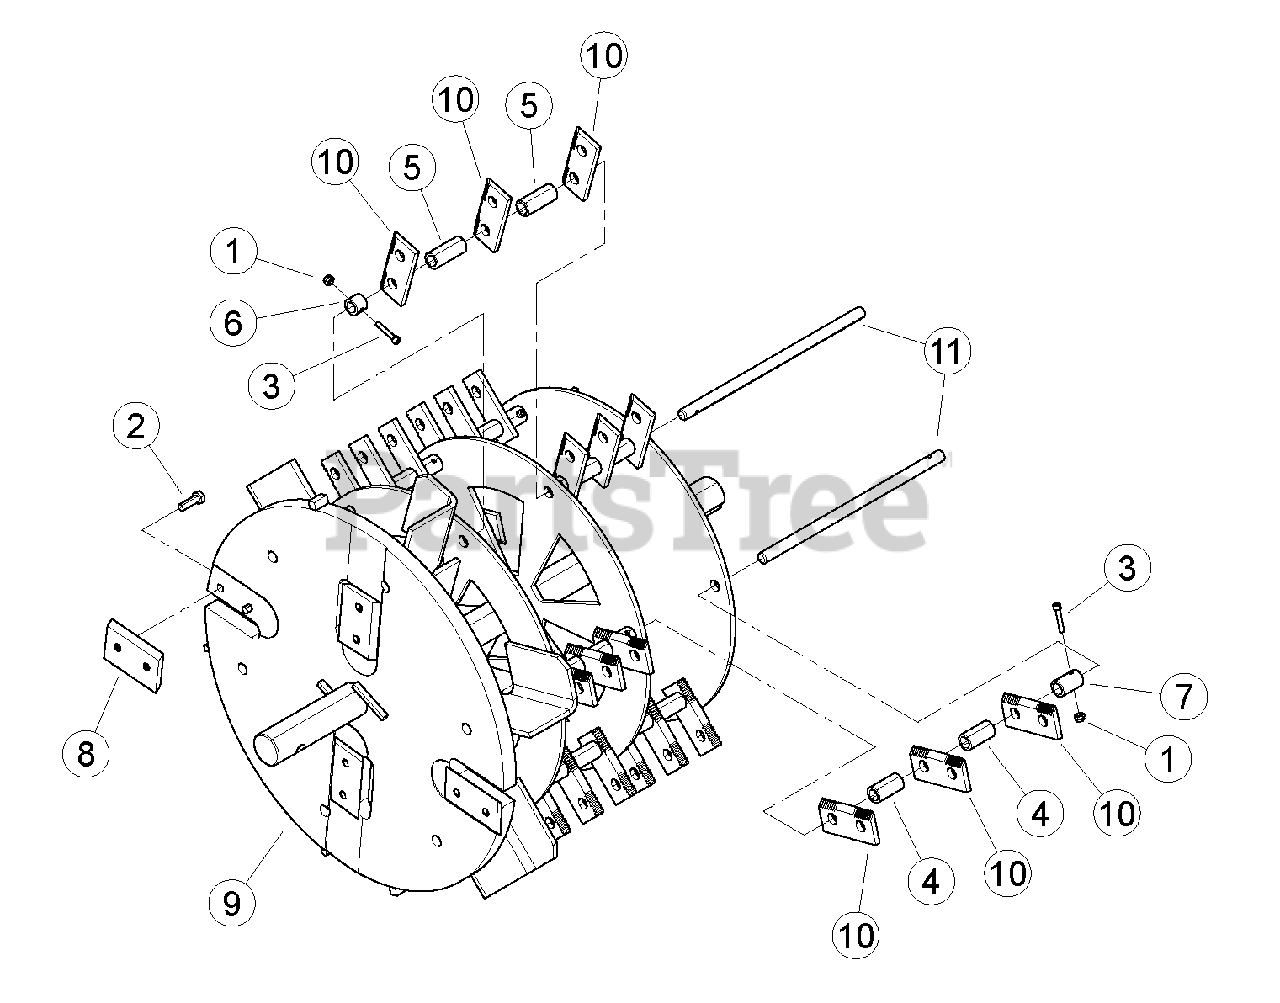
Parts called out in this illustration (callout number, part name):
1	NUT, 10/24 NYLOCK TYPE NM, ZP
2	BOLT, 5/16-18 X 1"GR8 HCS PATCH ZP
3	SCREW, #10-24 X 1-1/8" PL SKT HD CAP
4	SPACER, 0.75 X 0.51 X 1.44
5	SPACER, 0.75 X 0.51 X 1.74
6	SPACER, .75 X .59 W/ HOLE
7	SPACER, .75 X 1.18 W/ HOLE
8	KIT, CHIPPER BLADE
9	WELDMENT, 5 INCH C/S ROTOR
10	KIT, SC5627B SHREDDER KNIVES
11	SHAFT, .50 X 10.875
